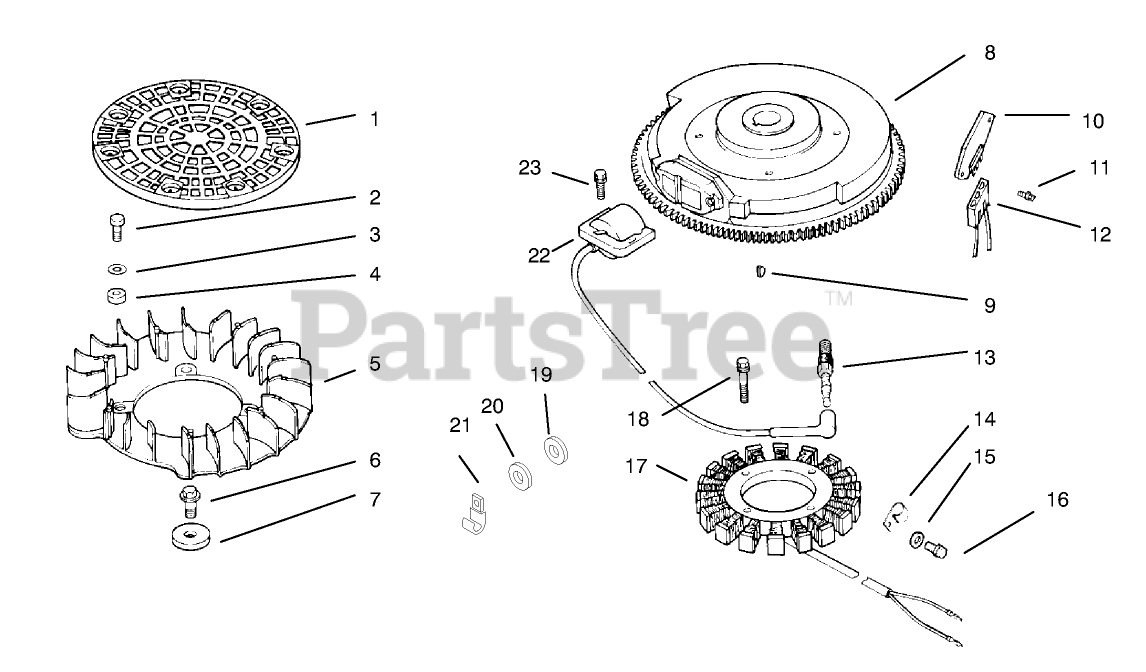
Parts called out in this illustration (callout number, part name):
1	Screen-Grass (Only On: 72103, 72083)
2	Screw-Hex.
3	Washer
4	Spacer-Fan (Only On: 72103)
5	Fan (Only On: 72103, 72083)
7	Spacer-Fan
8	Flywheel ASM (Only On: 72103, 72083)
10	Rectifier-Regulator
12	Connector
13	Spark Plug
16	Screw
17	Stator-15 amp
19	Washer
20	Washer
22	Module-Ignition
